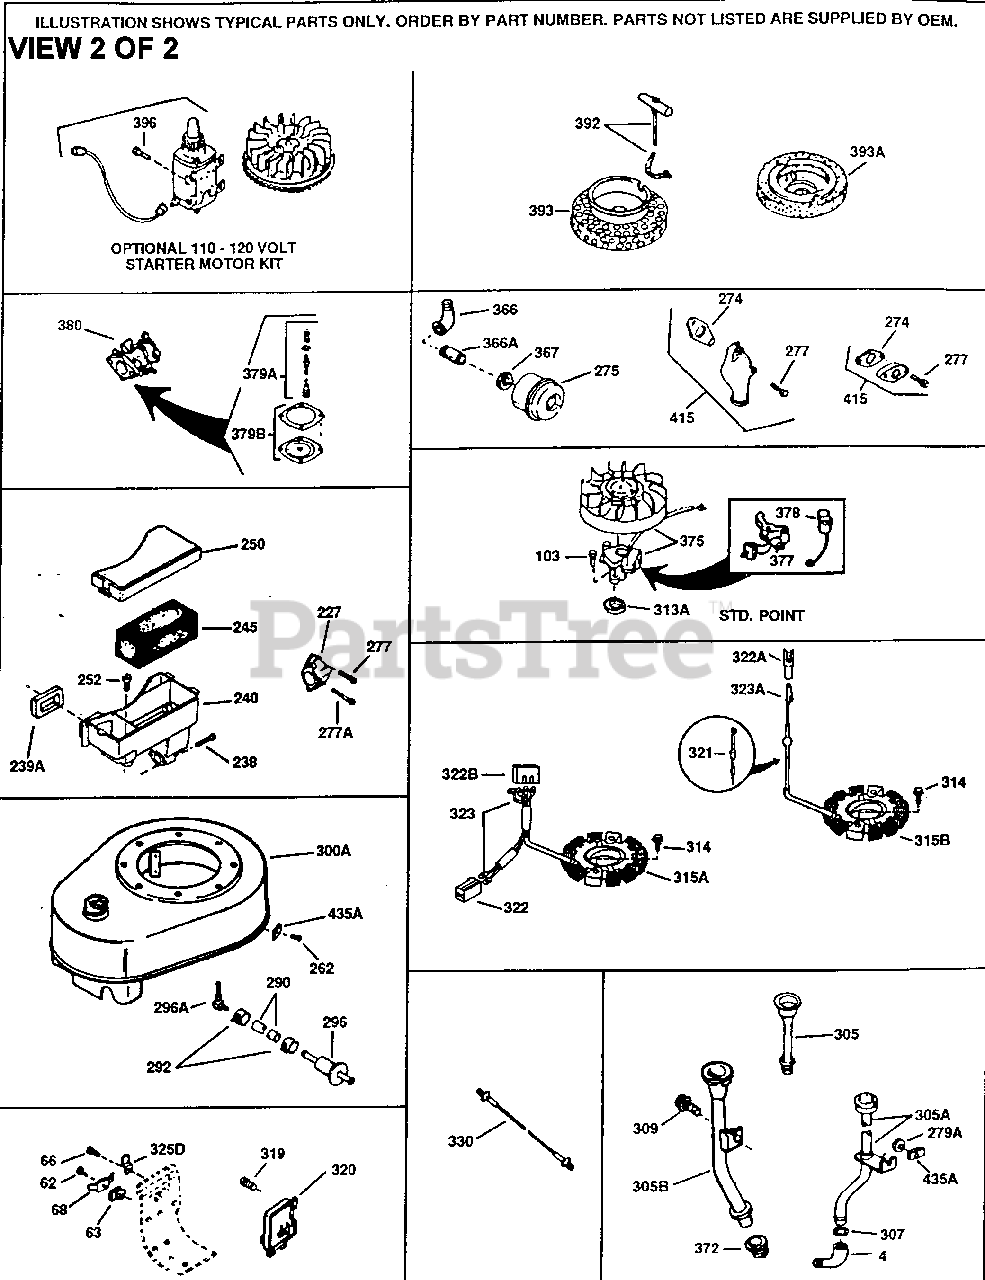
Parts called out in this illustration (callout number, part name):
62	Screw, 8-32 x 3/8"
63	Breather Tube Grommet
64	Screw, T-30, 1/4-20 x 1/2"
68	Ground Terminal
72B	Oil Drain Plug (3/8-18)
103	Screw, Torx T-15, 10-24 x 1"
239A	* Air Cleaner Gasket
240	Air Cleaner Body
245	Air Cleaner Filter
250	Air Cleaner Cover
252	Screw, 10-24 x 11/16"
262	Screw, T-40, 5/16-24 x 21/32"
370A	Lubrication Decal
380	Carburetor (Incl. 184)
513	Intake Pipe Screen
